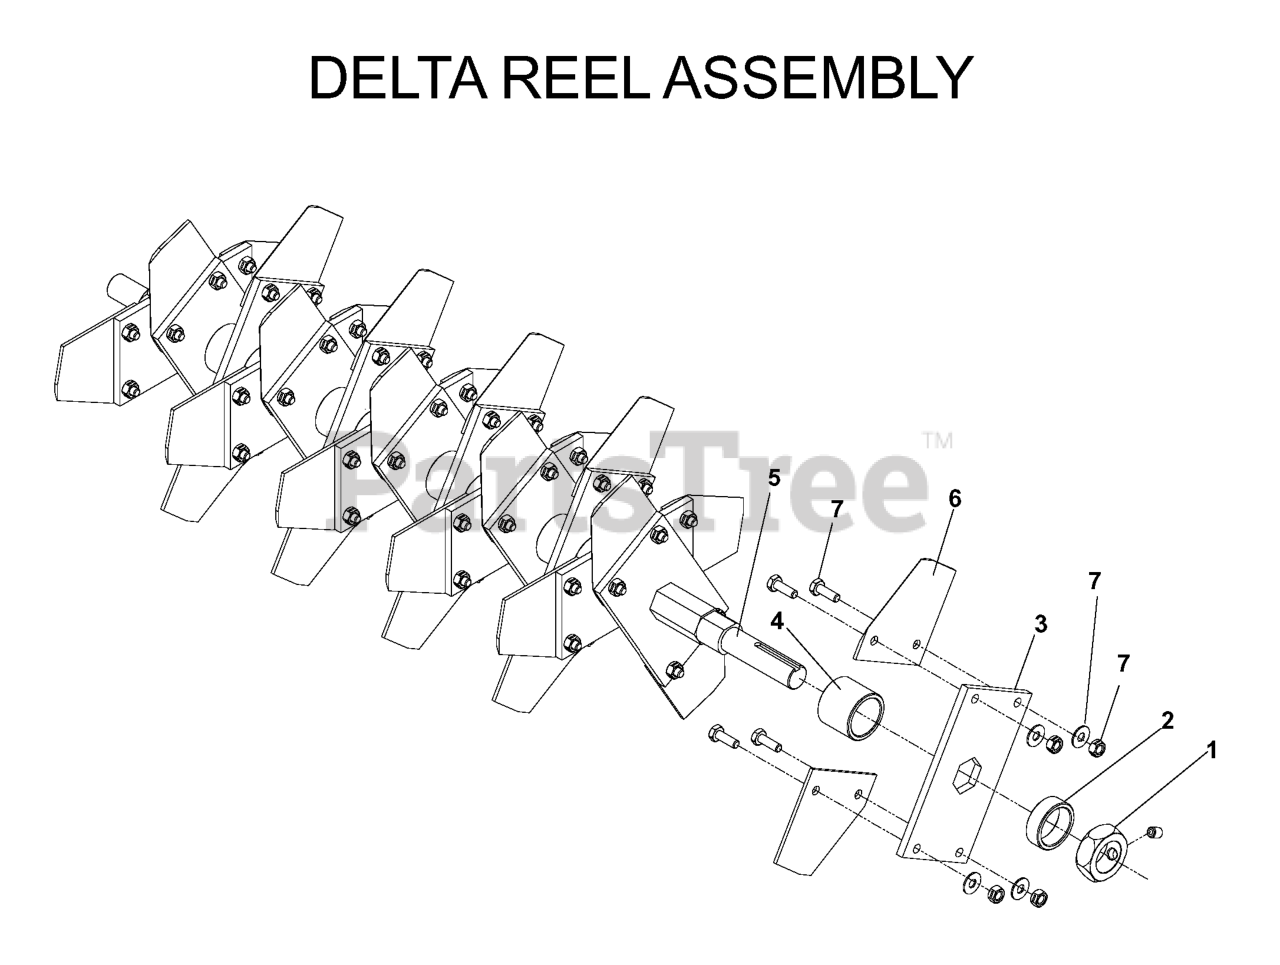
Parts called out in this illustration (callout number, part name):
1	JAM NUT W/SET SCREW
2	END SPACER
3	BLADE MOUNTING PLATE
4	SPACER - LONG
6	30 DELTA SET W/HARDWARE
7	SCREW & NUT (60 EACH)
539107184	22" DELTA REEL (COMPLETE)
